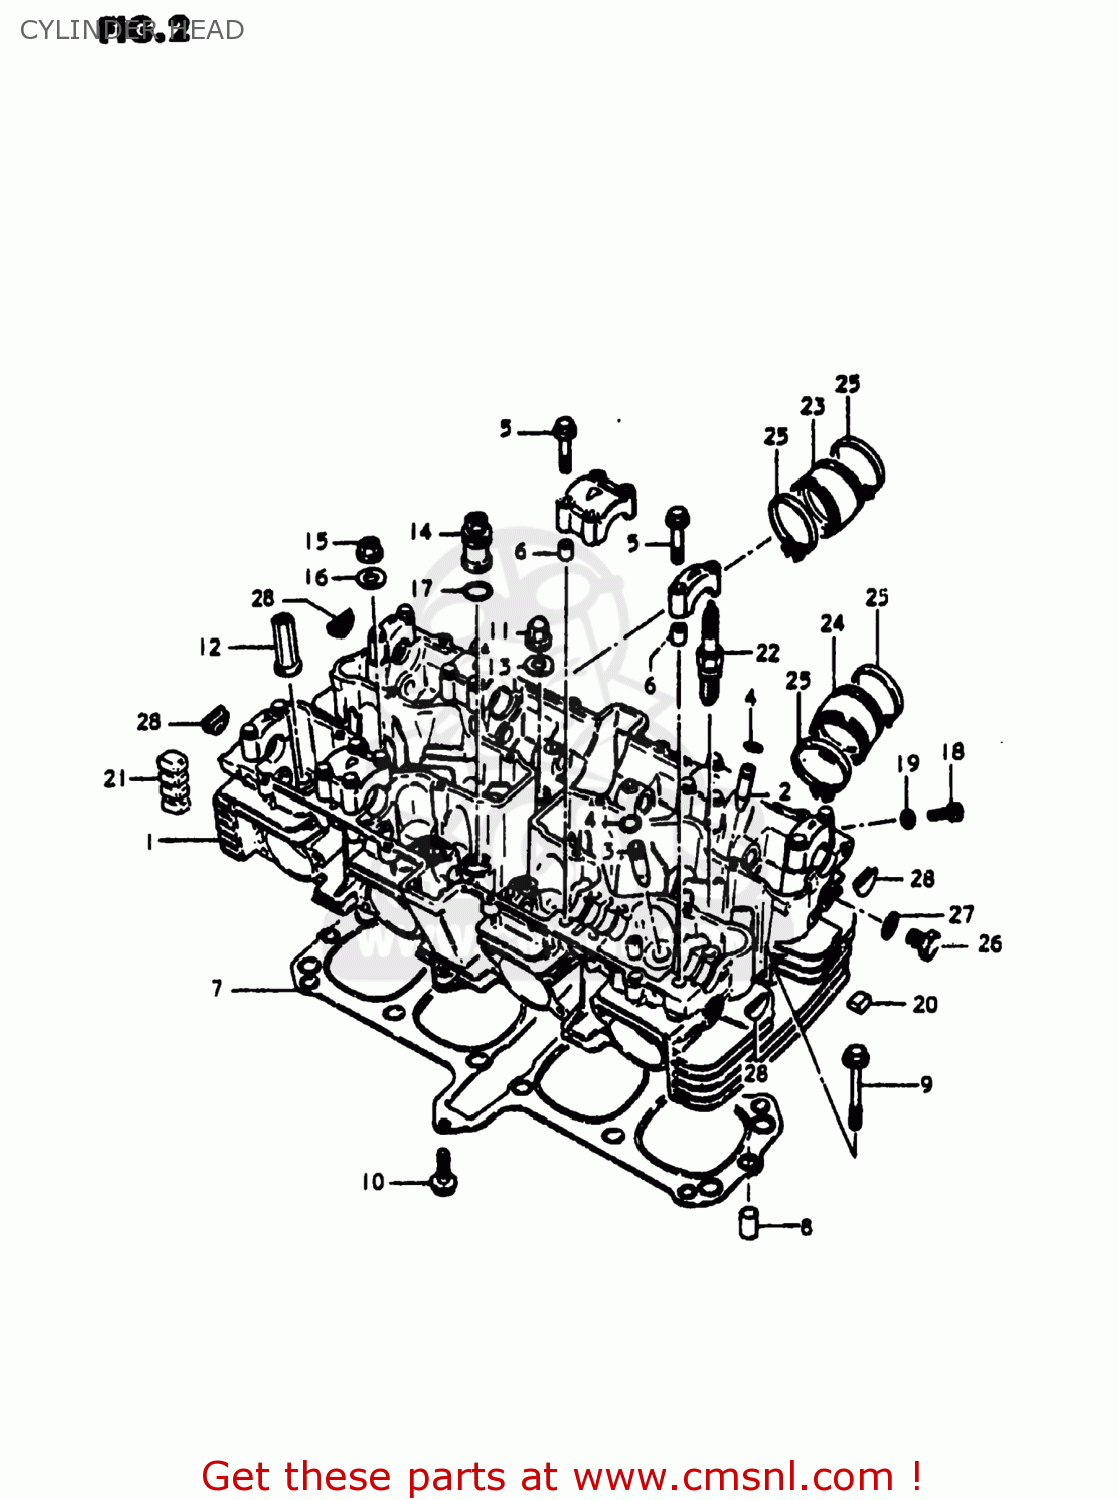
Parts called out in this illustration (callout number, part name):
1	HEAD ASSEMBLY,CYLINDER
2	GUIDE,INTAKE VALVE
3	GUIDE,INTAKE VALVE
4	RING,SNAP
5	BOLT(6X39)
6	PIN(6.2X8X11)
7	GASKET,CYLINDER HEAD (NAS)
8	PIN
9	BOLT
10	BOLT
11	NUT
12	NUT
13	GASKET(10.5X22X2) (NAS)
14	NUT,CYLINDER HEAD SEAL
15	NUT
16	WASHER(10.5X22X2.3)
17	O RING(D:2.4,ID:16.8)
18	BOLT
19	GASKET(5.3X9.3X1.2) (NAS)
20	PAD
21	PAD,CYLINDER
22	SPARK PLUG D8EA
23	PIPE,INTAKE,R
24	PIPE,INTAKE,L
25	CLAMP
26	PLUG (14X12)
27	GASKET(14X19.2X2) (NAS)
28	PLUG
